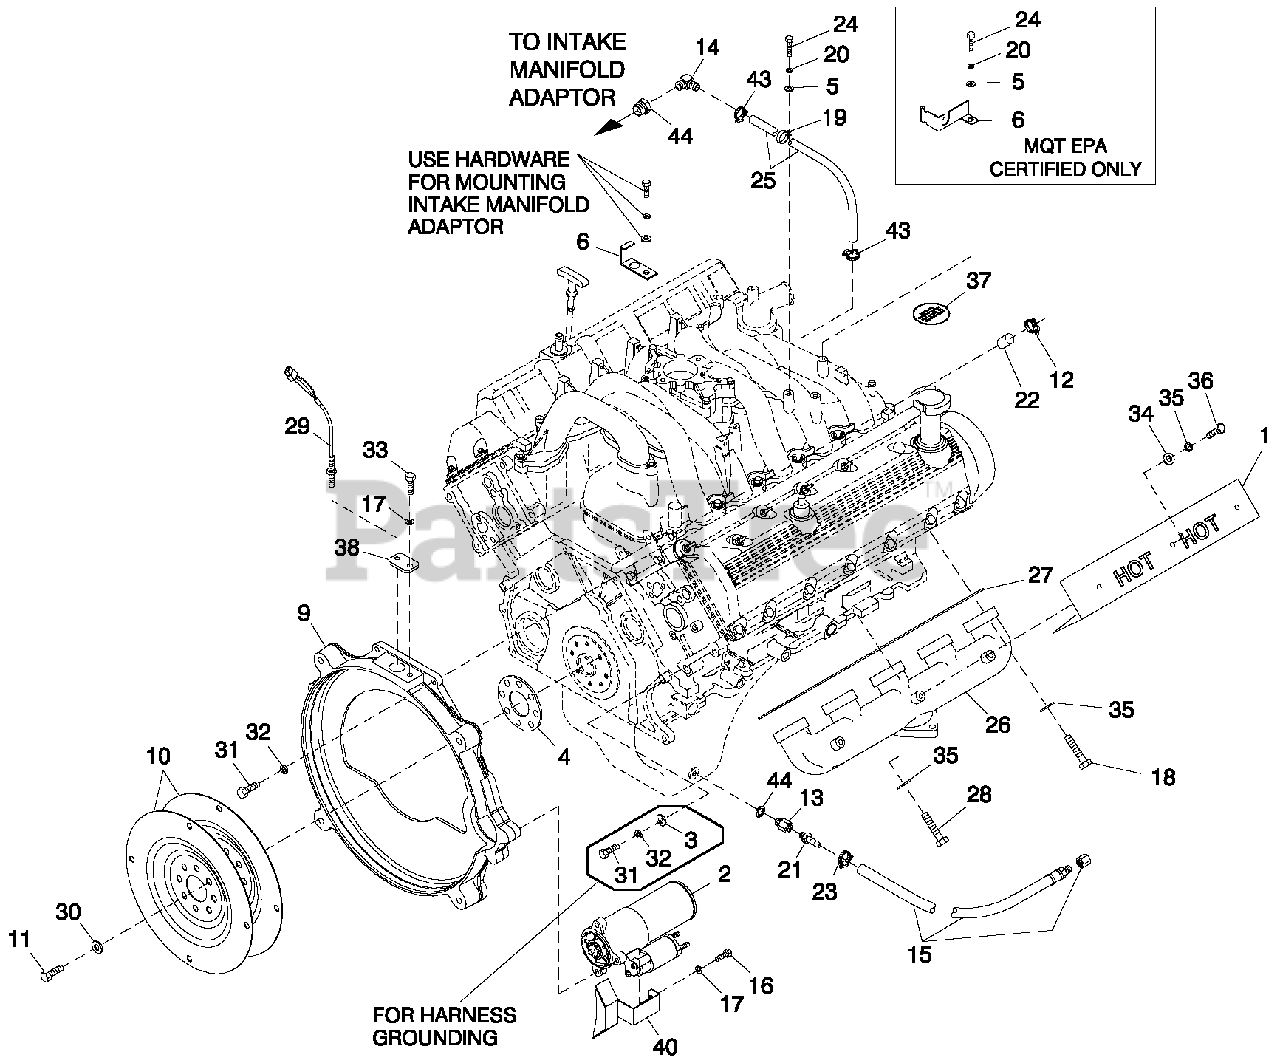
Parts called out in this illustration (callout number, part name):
1	HEAT SHIELD EXHAUST
2	STARTER MOTOR FORD V-10 ENGINE
3	WASHER FLAT 3/8-M10 ZINC
4	SPACER FLEXPLATE 5.4L/6.8L (1800 RPM UNITS ONLY)
5	WASHER FLAT 1/4-M6 ZINC
6	BRACKET SIGNAL CONDITIONER
8	WASHER NYLON .565
9	ENGINE ADAPTER 5.4L/6.8L
10	FLEX PLATE 2 POLE (1800 RPM UNITS ONLY)
11	SCREW HHC M10-1.0 X 25 G10.9
12	CLAM P HOSE #10 .56 - 1.06 (1800 RPM UNITS ONLY)
13	ADAPTER M14-1.50X 3/8 N PT
14	BARBED EL 90 3/8N PTX5/8
15	HOSE DRAIN ASSY 28"
16	SCREW HHC M8-1.25 X 30 G8.8
17	WASHER LOCK M8-5/16
18	SCREW SHC M8-1.25 X 35 SS
19	CLAM P VINYL .7 5 X .343Z
20	WASHER LOCK M6-1/4
21	BARBED STR 3/8 NPT X 3/8
22	CAP HOSE (1800 RPM UNITS ONLY)
23	CLAMP HOSE .38-.87
24	SCREW HHC M6-1.0X 16 G8.8
25	HOSE COOL 5/8" ID 250#W P (14")
26	EXH MANIFOLD MACH 6.8L V-10
27	GASKET EXHAUST MANIFOLD
28	SCREW HHC M8-1.25 X 35 SS G8.8
29	ASSY MAGPICKUP (3/8-24 MALE)
30	WASHER FLAT .43X1.00
31	SCREW SHC M10-1.5 X 25 G12.9
32	WASHER LOCK M10
33	SCREW HHC M8-1.25X2 0 G8.8
34	WASHER FLAT M8 SS
35	WASHER LOCK M8 SSTL
36	SCREW HHC 5/16-18 X 1/2 SSTL
37	DECAL REFER TO OWNERS MANUAL
38	PLATE MAG PICK-UP ADAPTOR
40	COVER STARTER 5.4 & 6.8 FORD CPL
43	CLAMP HOSE #10 .56-1.06
44	ADAPTOR 1/4" NPT TO 3/8" NPT
